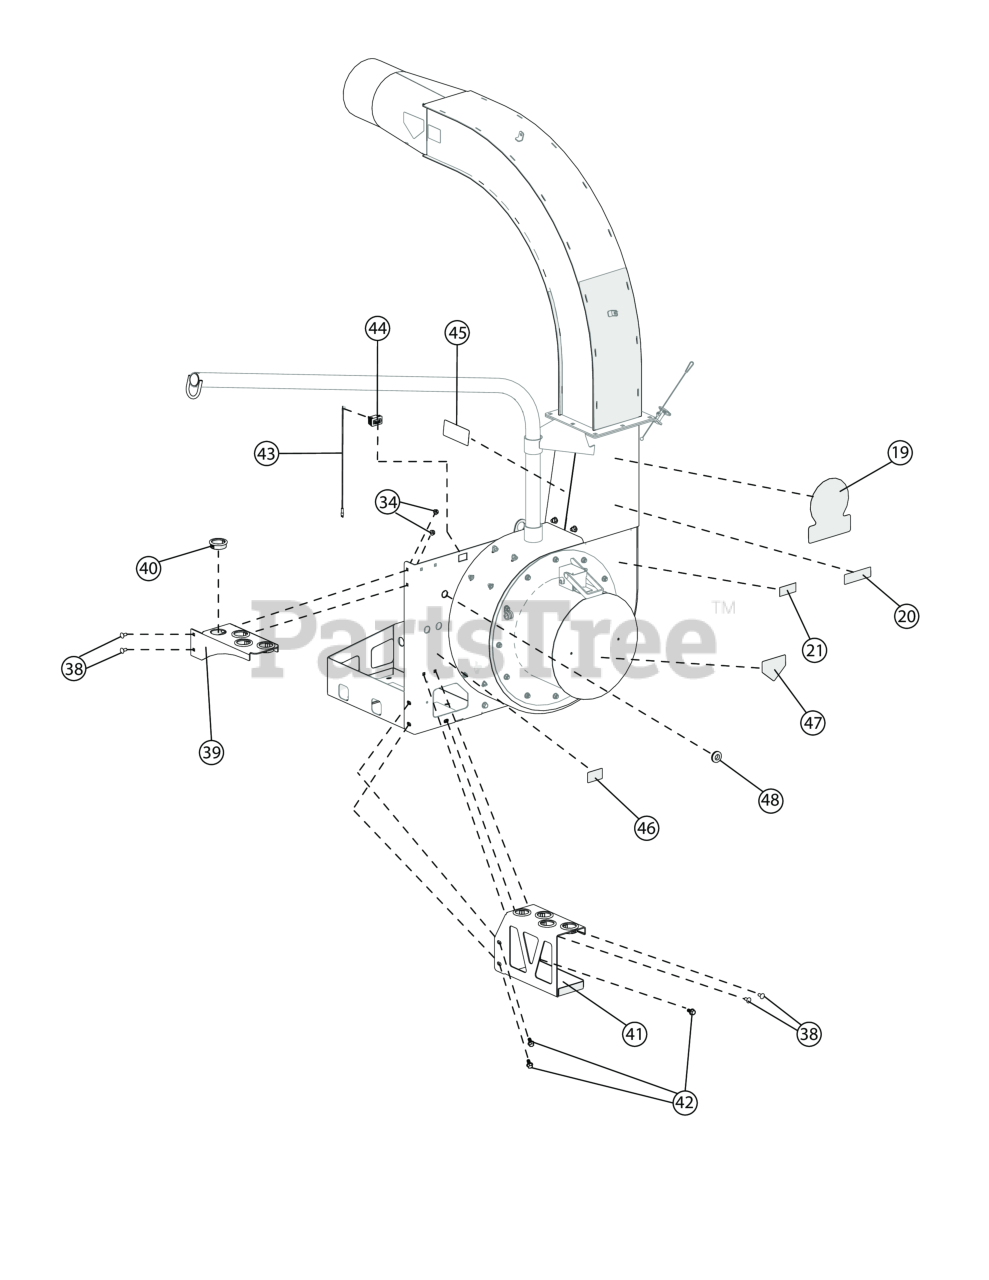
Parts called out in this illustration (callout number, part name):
19	LABEL, DL SERIES
20	LABEL DL PIRANHA
21	LABEL, WARNING LINER DL
34	NUT-HEX-NYLK, FLG .3125-18 ZP
38	BOLT CARRIAGE 5/16"-18 X 3/4" ZP
39	RAKE HOLDER, UPPER DL
40	BUSHING, SNAP 1.81" ID
41	RAKE HOLDER, LOWER DL
42	SER HEX WASHER 3/8" - 16
43	WIRE, ASSY HOUR METER DL29/37
44	HOURMETER, INDUCTIVE PANEL MOUNT
45	LABEL WARNING ENGINE OVERHEAT
46	LABEL EPA COMPLIANCE 49 STATE DL29/37
47	LABEL WARNING OPEI
48	GROMMET 1" HOLE
